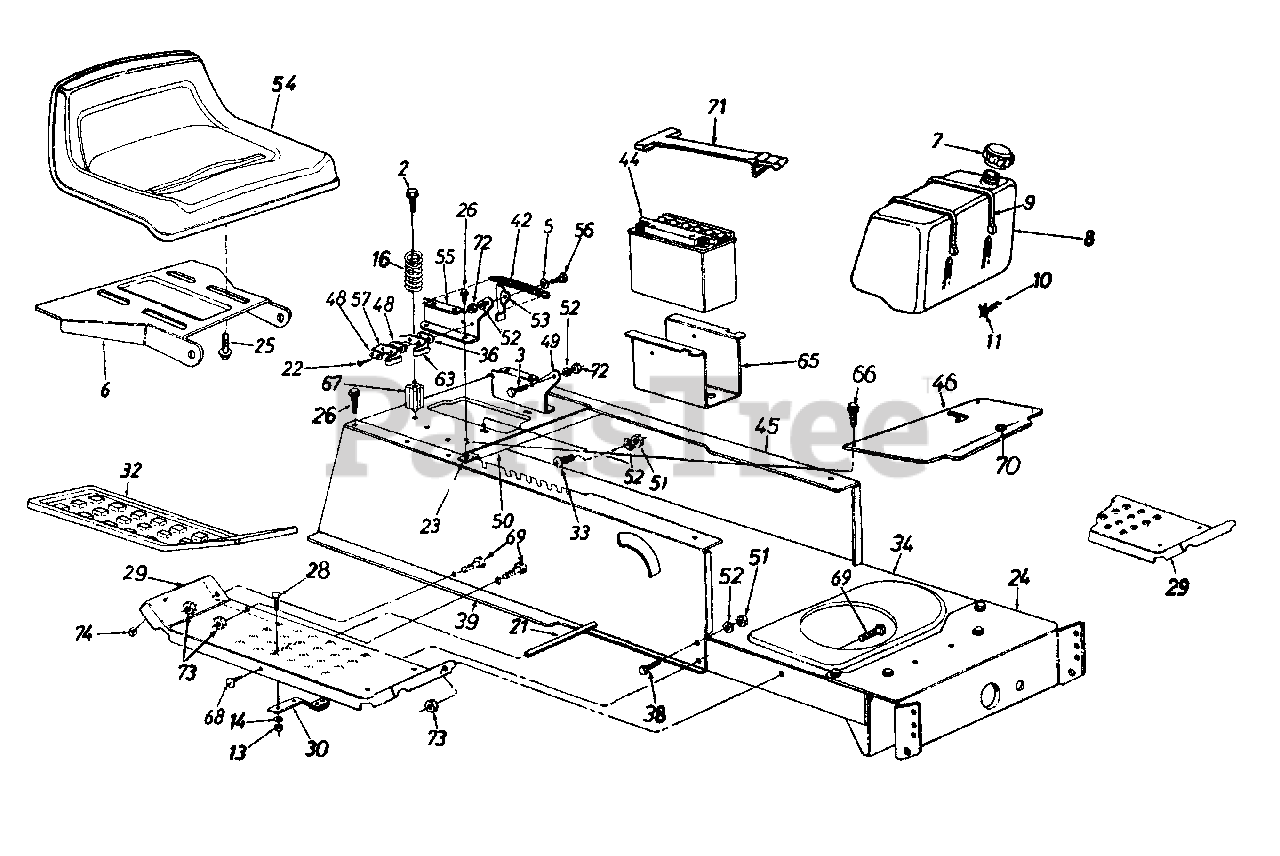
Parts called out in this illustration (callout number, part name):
2	Hex Tap Scr. 5/16-18 x 3.25"
3	Screw
5	Washer
7	Fuel Cap
8	Fuel Tank (12.5 H.R & Smaller)
9	Tie Strap
10	Fuel Line
11	Hose Clamp
13	Hex Nut 1/4-20 Thd.
14	L-Wash. 1/4" I.D.
16	Compression Spring
21	Running Board Rod
22	Hex AB-Tap Scr. #8 x .50" Lg.
23	Speed Nut #10Z
25	Hex Tap Scr. 3/8-16 x .62" Lg.
26	Hex Wash. Hd. AB-Tap Scr.5/16 x .75" Lg.
28	Carriage Bolt 1/4-20 x .62"
32	Rubber Foot Pad-L.H.
36	Insulator Boss Plate
38	Hex Bolt 5/16-18 x .75" Lg.
44	12-V Battery
52	L-Wash. 5/16" I.D.
53	Seat Lift Brkt.
54	Seat 8-7/8" High
56	Shld. Bolt .437" Dia. x .268"
57	Spring Switch (Seat-Outer)
63	Safety Switch (Seat-Inner)
66	Truss Mach. B-Tap Scr.#10 x .5" Lg.
67	Spring Spacer
68	Truss Mach. Scr. 5/16-18 x .75"
69	Hex Bolt 5/16-18 x .75" Lg.
70	Snap Bushing
71	Battery Retainer Strap
72	Hex Nut 5/16-18Thd.
73	Hex Sems Nut 5/16-18 Thd.
74	Hex Sems Nut 1/4-20 Thd.
